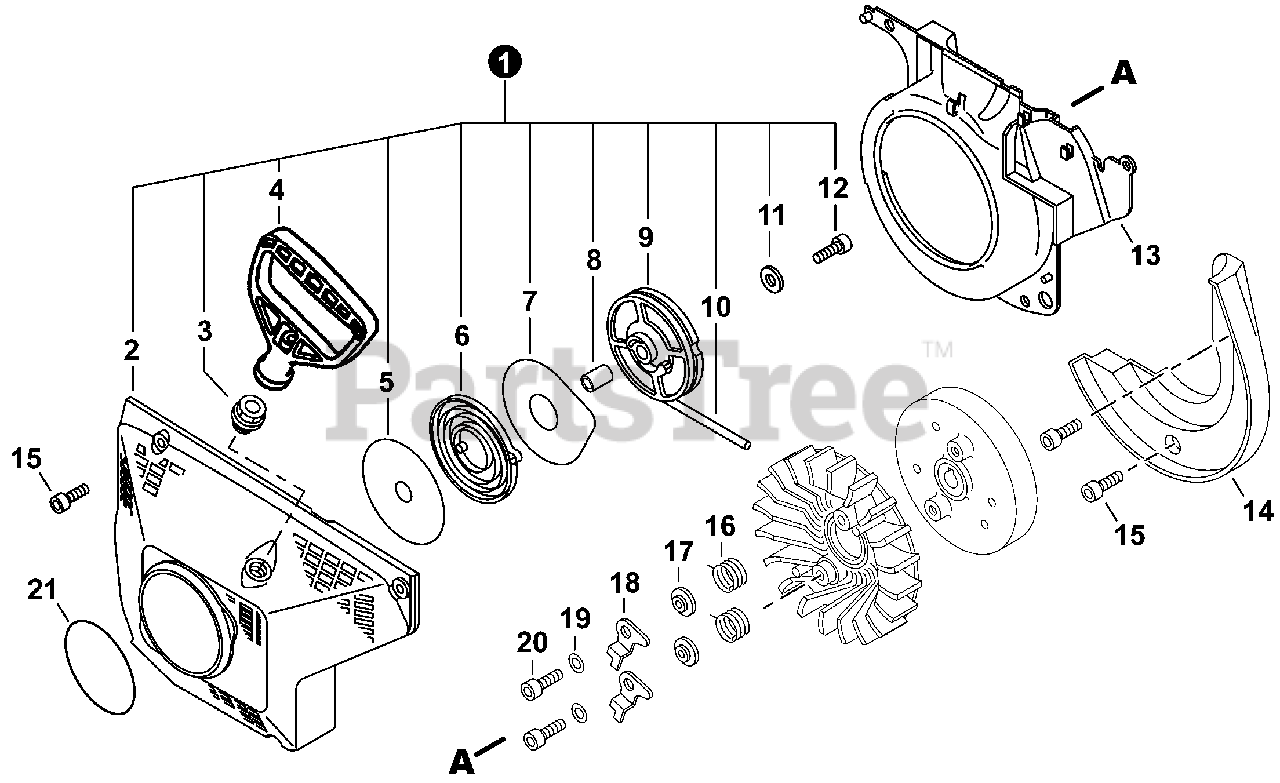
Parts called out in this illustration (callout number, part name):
1	STARTER ASSY - GRAY
1	STARTER ASSY - ORANGE
2	CASE, STARTER - ORANGE
3	GUIDE, ROPE
4	GRIP, STARTER
5	PLATE, STARTER
6	SPRING, RECOIL
7	PLATE, STARTER
9	REEL, ROPE
10	ROPE, STARTER 4.0x950
11	WASHER 5.2x16x1.0
12	BOLT 5x14
13	COVER, FAN - GRAY
13	COVER, FAN - ORANGE
14	PLATE, GUIDE - ORANGE
15	BOLT 5x20
16	SPRING, RETURN
17	SPACER, PAWL
18	PAWL, STARTER
19	WASHER 5.5x12x0.8
20	BOLT 5x30
21	LABEL - ECHO
